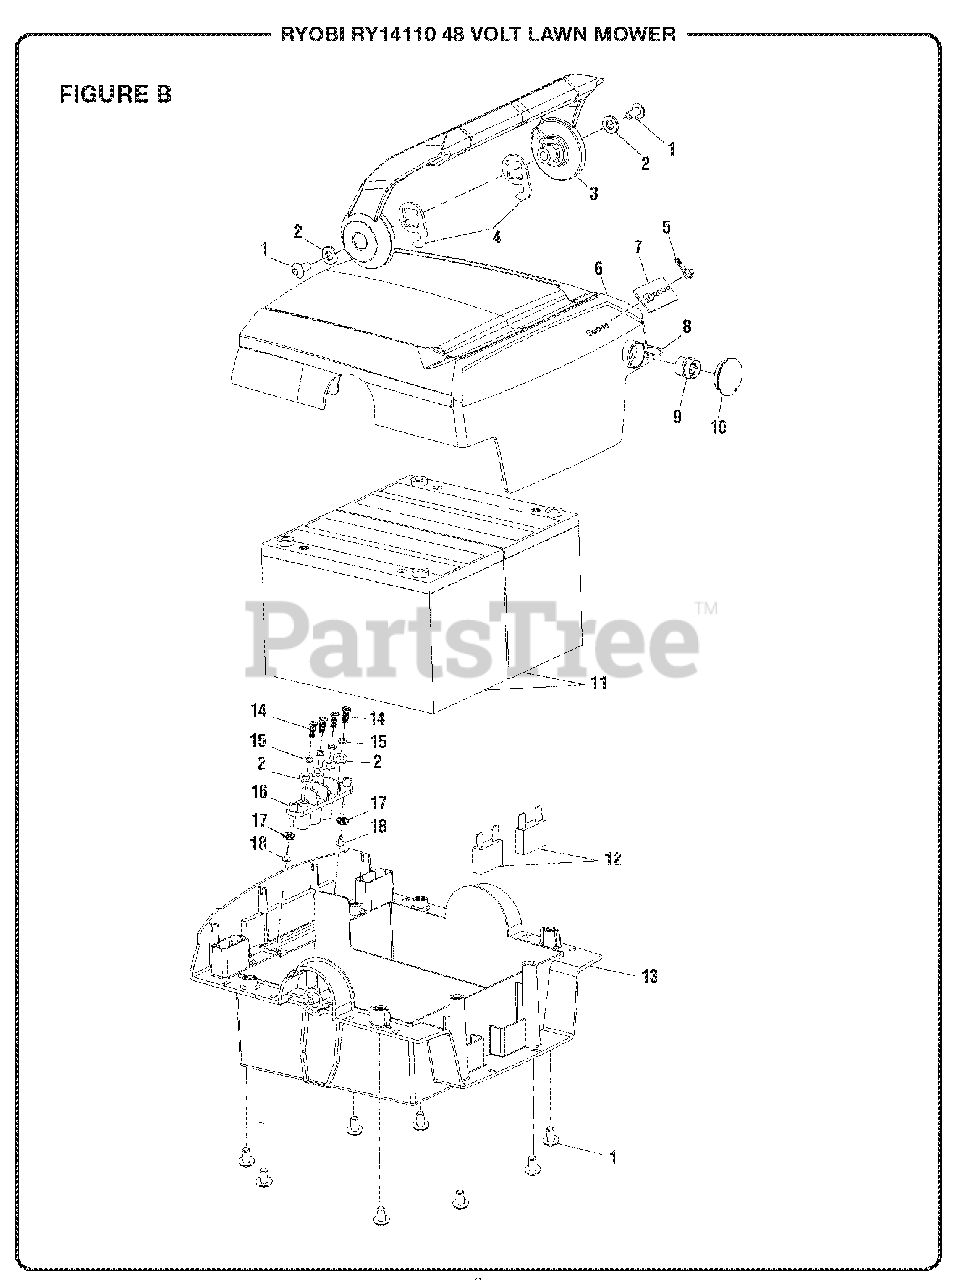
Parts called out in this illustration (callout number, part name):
1	Screw (4.2 x 18 mm, Pan Hd.)
2	Washer (M5)
3	Battery Handle
4	Battery Hook
5	LED Battery Meter
6	Battery Cover
7	Battery Display Board
9	Charger Port
10	Battery Recepticle Cover
11	Battery Cell
12	Fuse (60 Amp)
13	Battery Case
14	Screw (M5 x 6 mm)
15	Lock Washer (M5)
16	Upper Connector
17	Washer (M4)
18	Screw (M3.5 x 12 mm, Pan Hd.)
